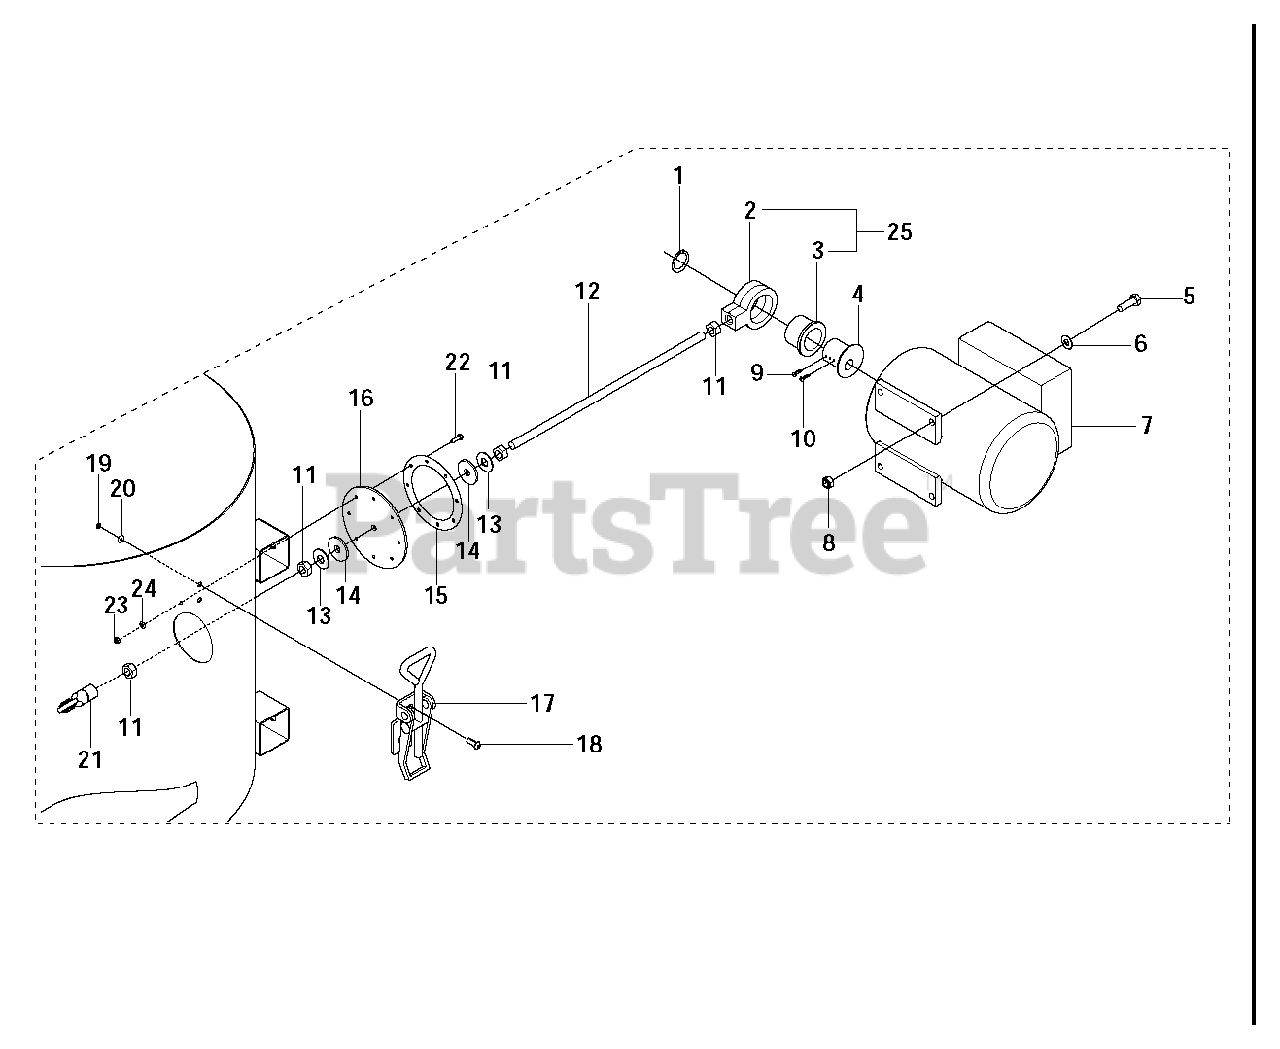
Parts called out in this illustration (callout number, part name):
6	WASHER
8	HEXAGON LOCKING NUT
13	WASHER
19	HEXAGON LOCKING NUT
23	HEXAGON LOCKING NUT
24	WASHER
